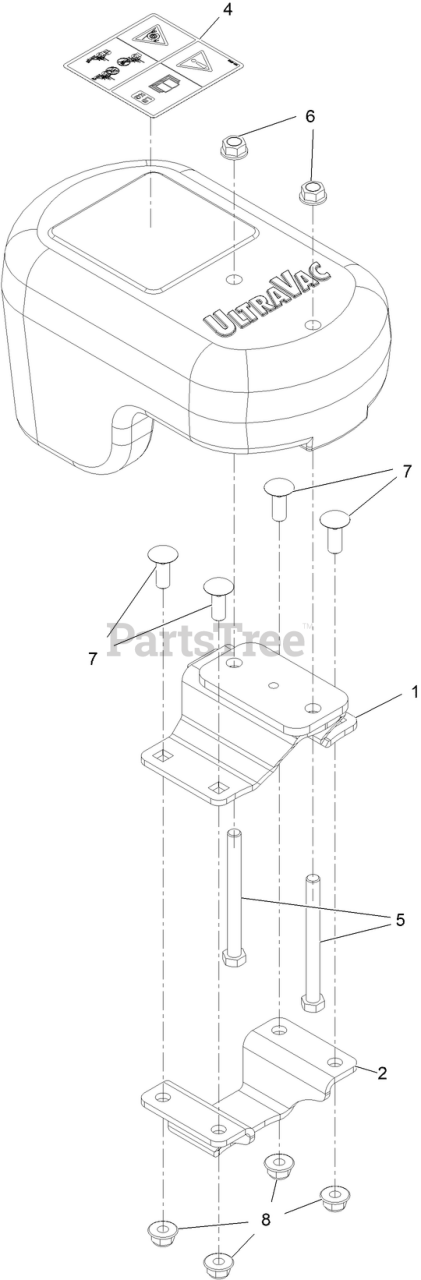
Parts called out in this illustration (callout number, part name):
1	WELD-CASTER WEIGHT BRACKET
2	BRACKET-CASTER WEIGHT BTM
4	DECAL-WARNING, TRACTION
5	SCREW-HH
6	NUT-HHF, WHIZ
7	SCREW-CARR
8	NUT-HF, NI
